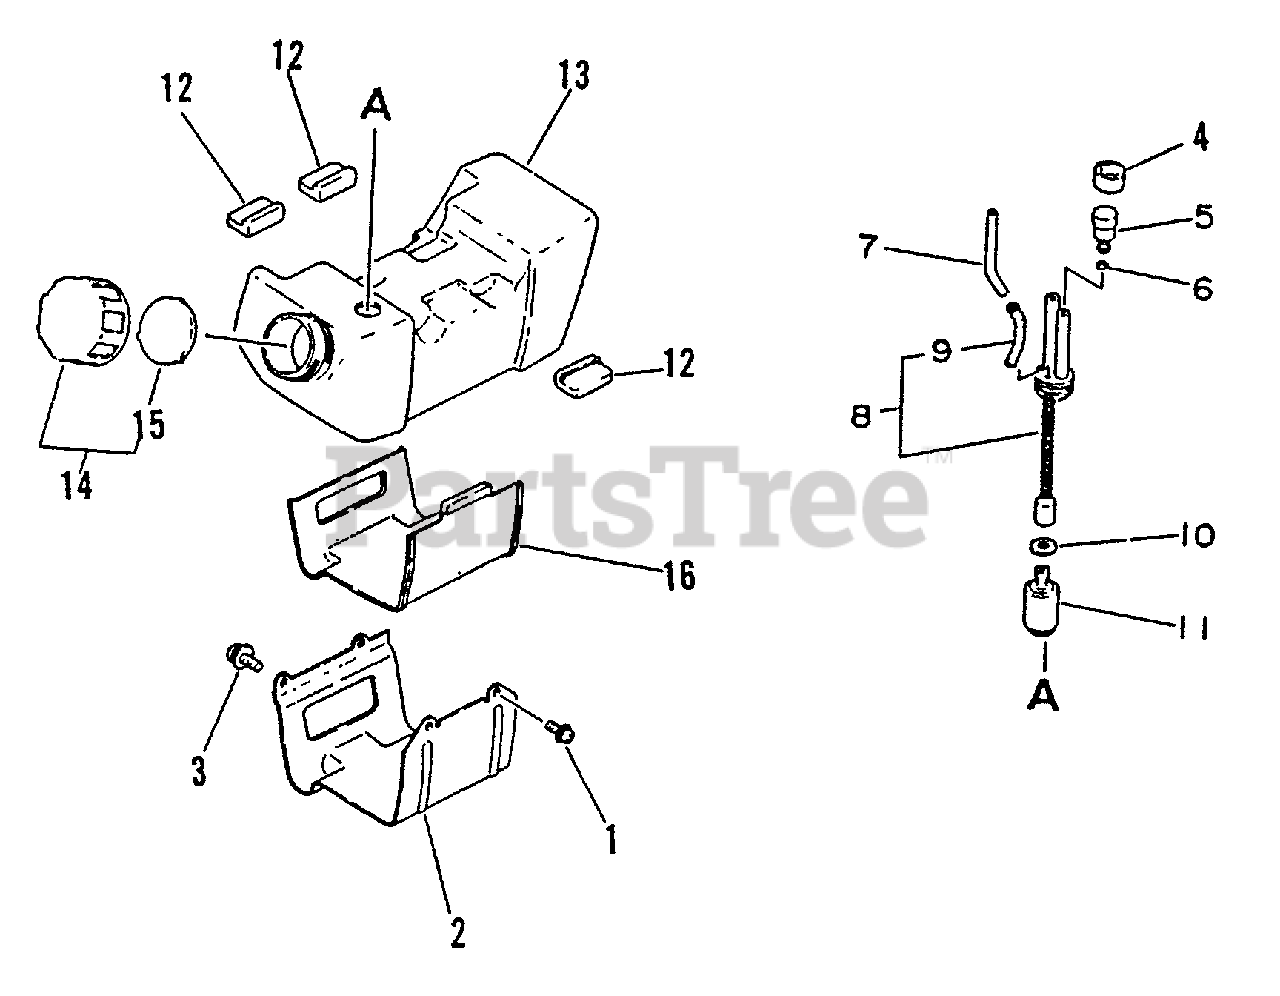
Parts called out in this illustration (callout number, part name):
1	SCREW - 4X10
2	BRACKET, FUEL TANK
3	SCREW - 5X12
4	COVER, VENT
5	VENT, FUEL TANK
6	CLIP - 5.5
7	PIPE - 3X5X50 -- BLACK
8	FUEL SYSTEM KIT
9	CONNECTOR, PIPE
10	WASHER - 5
11	FILTER, FUEL
12	CUSHION, FUEL TANK
13	TANK, FUEL
14	CAP ASSY
15	GASKET, CAP
